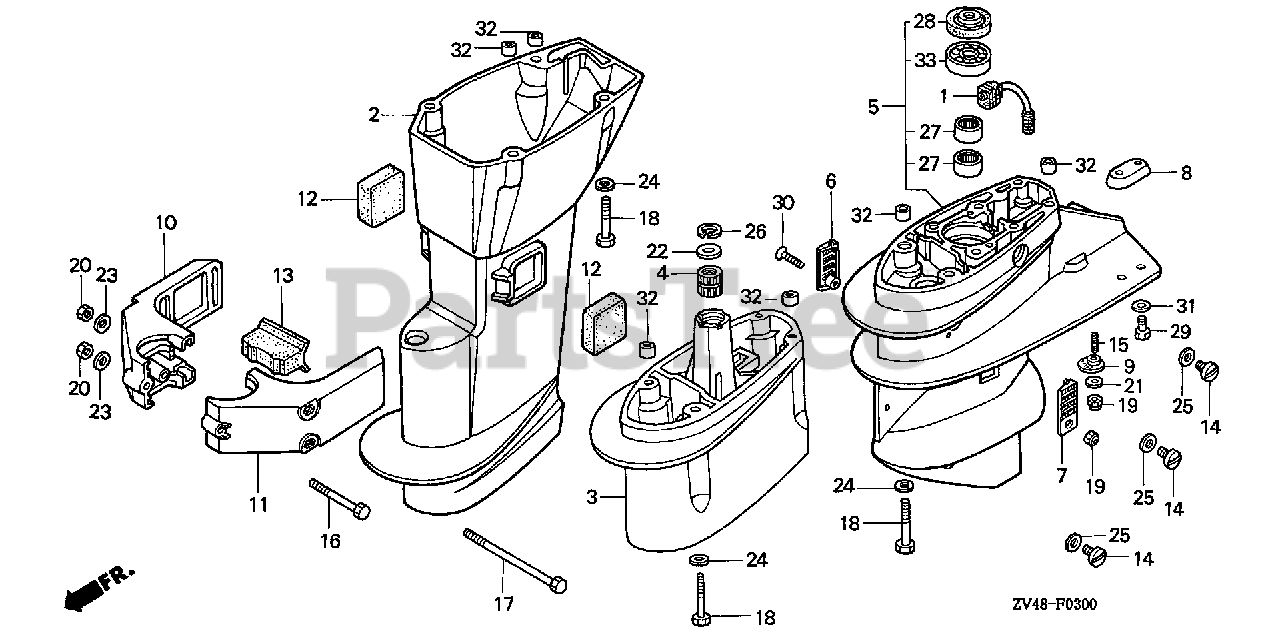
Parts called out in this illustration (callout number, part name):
1	TUBE, WATER (LOWER)
2	CASE, EXTENSION *NH282MU* (L) (OYSTER SILVER METALLIC-U)
3	SEPARATOR, EXTENSION *NH282MU* (UL) (OYSTER SILVER METALLIC-U)
4	BUSH, VERTICAL SHAFT
5	CASE, GEAR *NH282MU* (OYSTER SILVER METALLIC-U)
6	SCREEN, R. WATER
7	SCREEN, L. WATER
8	METAL, ANODE
9	SCREEN, WATER (LOWER)
10	HOUSING, R. MOUNTING (LOWER) *NH282MU* (OYSTER SILVER METALLIC-U)
11	HOUSING, L. MOUNTING (LOWER) *NH282MU* (OYSTER SILVER METALLIC-U)
12	RUBBER, MOUNT (LOWER) (A)
13	RUBBER, MOUNT (LOWER) (B)
14	BOLT, OIL CHECK (8X8)
15	BOLT, STUD (5X16)
16	BOLT, HEX. (6X45)
17	BOLT, HEX. (6X130)
18	BOLT, HEX. (8X50)
19	NUT, SELF-LOCK (5MM)
20	NUT, HEX. (6MM)
21	WASHER, PLAIN (5MM)
22	WASHER (20MM)
23	WASHER, PLAIN (6X13X1.5)
24	WASHER, PLAIN (8MM)
25	WASHER, NYLON (8MM)
26	CIRCLIP, INNER (30MM)
27	BEARING, NEEDLE (15X21X12)
28	SEAL, WATER (15MM) (NOK)
29	BOLT, HEX. (6X18)
30	SCREW, OVAL (5X25)
31	WASHER, PLAIN (6MM)
32	PIN A, DOWEL (10X14)
33	BEARING, RADIAL BALL (6302)
